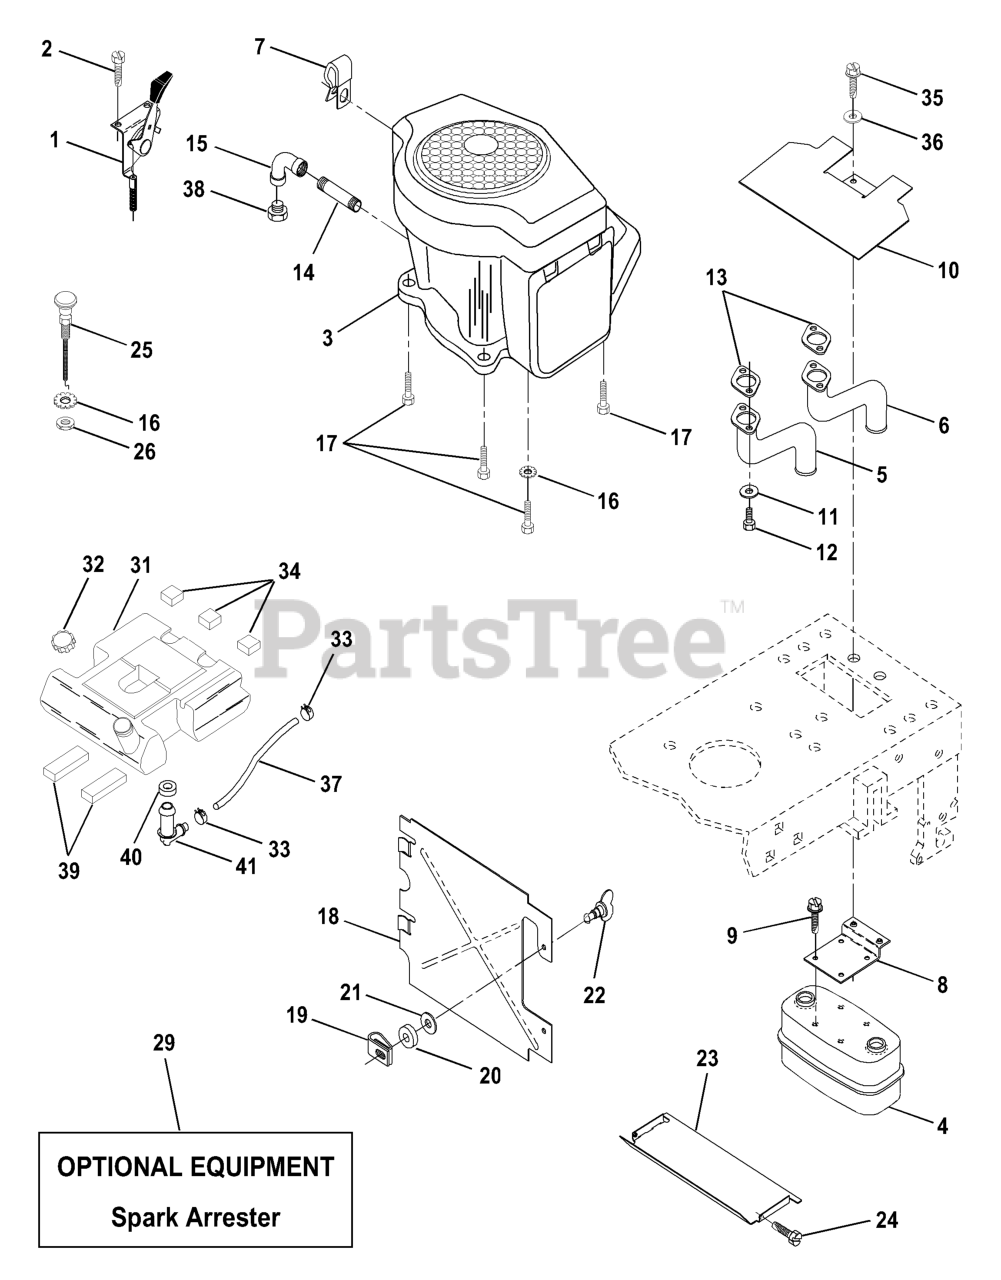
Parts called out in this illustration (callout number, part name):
1	THROTTLE CONTROL
2	SCREW LT
4	MUFFLER
5	MANIFOLD TUBE LH
6	MANIFOLD TUBE RH
7	CLIP T
8	BRACKET MUFFLER
9	SCREW ST
10	HEAT SHIELD
11	WASHER.LOCK.HVY.HLCL.SPR.5/16
12	Screw Hex Skt 5/16-18 unc x 3/4
13	Muffler Gasket
14	Nipple Pipe 3/8 Npt X 4-1/2"
15	ELBOW
16	LOCKWASHER
17	SCREW LT
18	HEAT SHIELD
19	RECEPTACLE LT
20	RETAINER LT
21	SNAP BUSHING T
22	STUD 1/4 TURN
23	HEAT SHIELD
25	CHOKE CONTROL
26	NUT
29	KIT.SPARK ARRESTOR 794945 B&S
31	FUEL TANK
32	FUEL CAP
33	HOSE CLAMP
34	PAD-SPACER LT
35	SCREW.THDROL.5/16-18X3/4.TTY
36	WASHER
37	FUEL LINE 54"
38	Plug Oil Drain
39	PAD IDLER TI
40	BUSHING OUTLET T
41	STEM FUEL TANK
